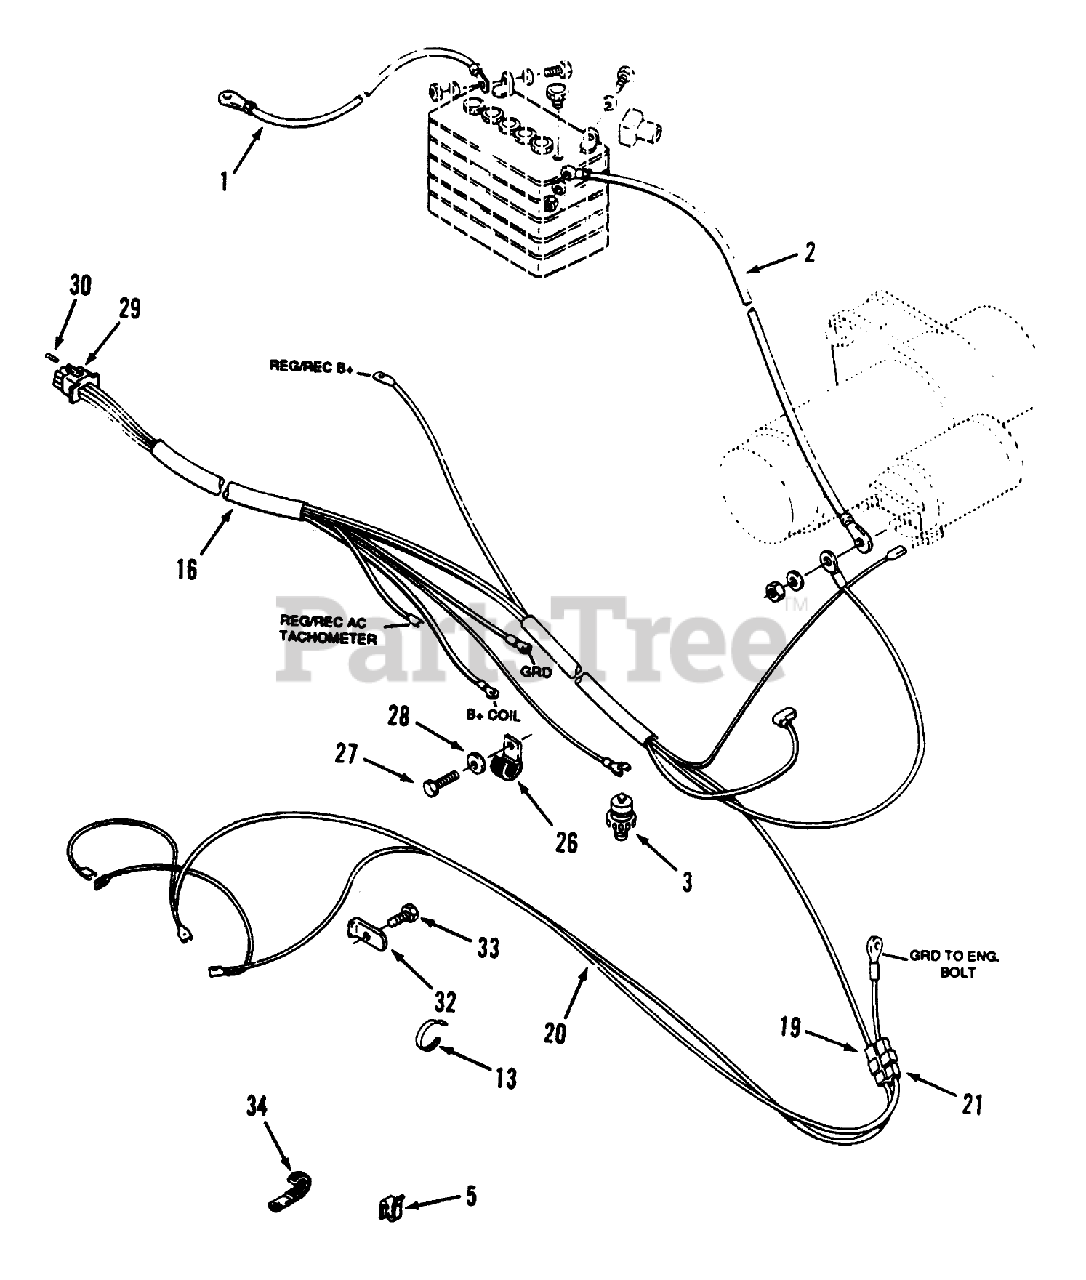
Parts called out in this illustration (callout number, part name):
1	Cable-Battery Ground
2	ASS'Y-WIRE
19	MALE CONNECTOR
21	CONNECTOR BODY
27	SCREW-HWH
30	CONTACT SOCKET
32	LOCK-HEADLIGHT
33	Bolt
34	CLIP
